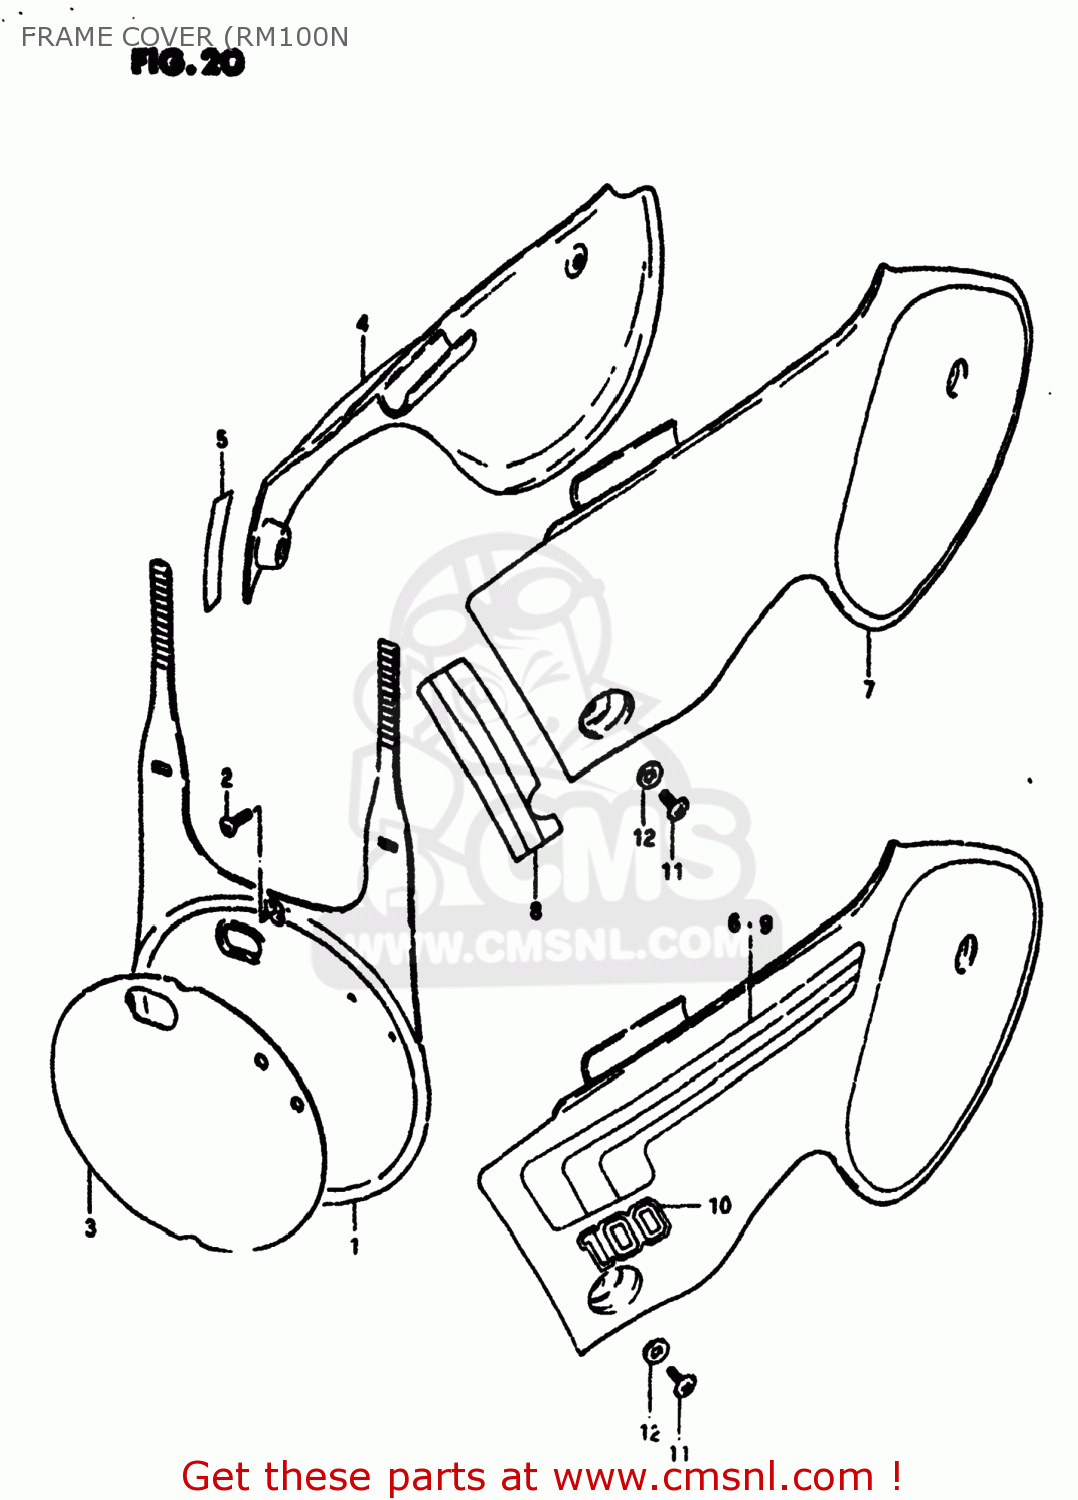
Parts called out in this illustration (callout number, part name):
1	PLATE,FR NUMBER
2	(5X20) CROSS SCREW
3	EMBLEM,FRONT NUMBER PLATE
4	COVER,FRAME,RIGHT
5	TAPE, RH
6	TAPE,FRAME COVER
7	COVER,FRAME,L(YELLOW)
8	TAPE,FRAME COVER,LEFT STRIPE
9	TAPE,FRAME COVER
10	EMBLEM
11	SCREW 6X12
12	WASHER
